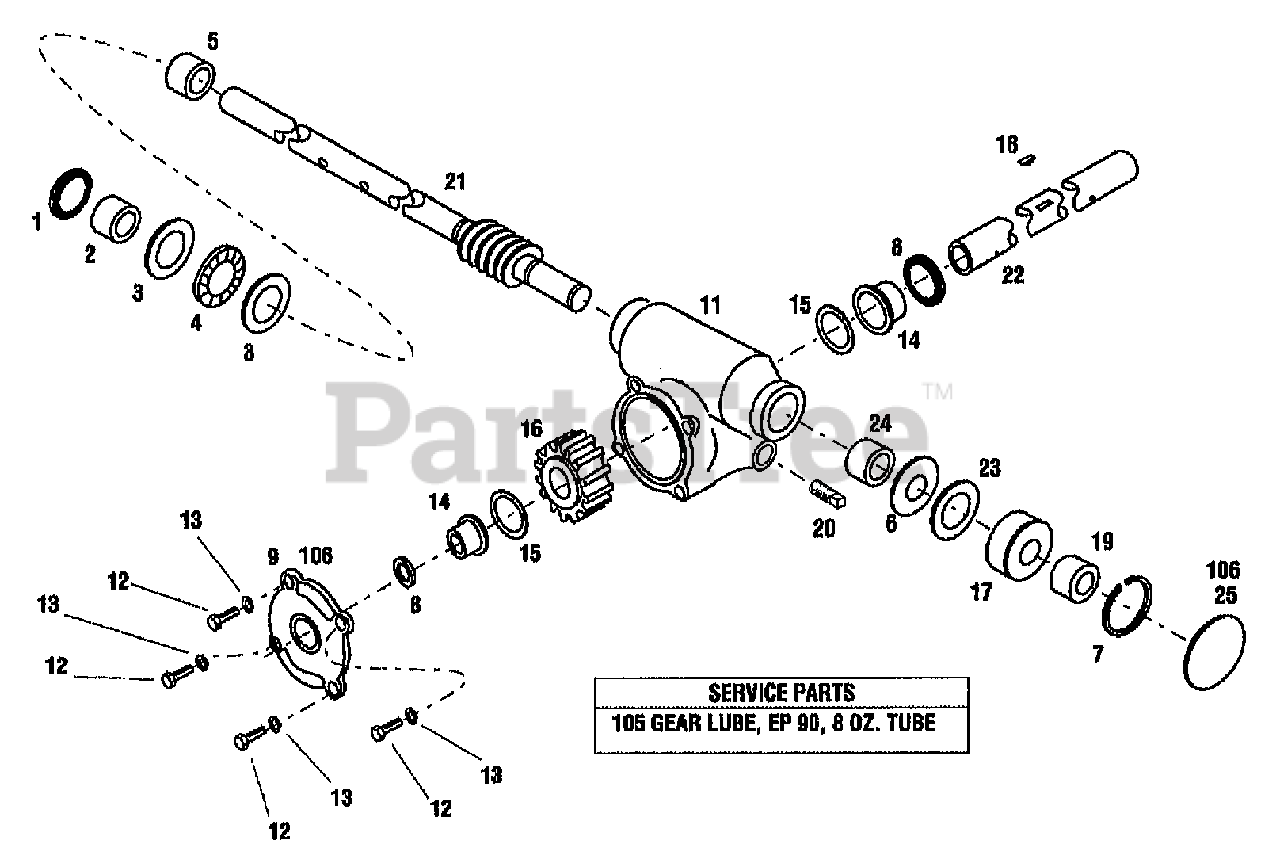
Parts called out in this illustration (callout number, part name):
1	SEAL-OIL 3/4 DIAMETER
2	BEARING-NEEDLE
3	RACE-THRUST
4	BEARING-THRUST
5	SPACER-1.0X.752X.302
6	WASHER
7	RING-RETAINING INTERNAL
8	SEAL-OIL
9	COVER-FLANGED
11	CASE ONLY-GEAR
12	SCR-HH 1/4-20X.625 G5 ZP
13	WASHER-LK .25 ZP
14	BUSHING-FLANGE
15	RACE-THRUST
16	GEAR-WORM 20 TEETH
17	SPACER-1.503X.749X.56
18	KEY-WOODRUFF .25X.875
19	BEARING-NEEDLE
20	PLUG-SQ HEAD 1/4-18 NPT
21	ASSM-SHAFT IMPELLER 21"
22	SHAFT-AUGER
23	RACE-THRUST
24	SPACER-.812X.566X.448
25	PLUG-EXPANSION
105	GREASE-LUBRICANT 55GAL
106	SEALANT
